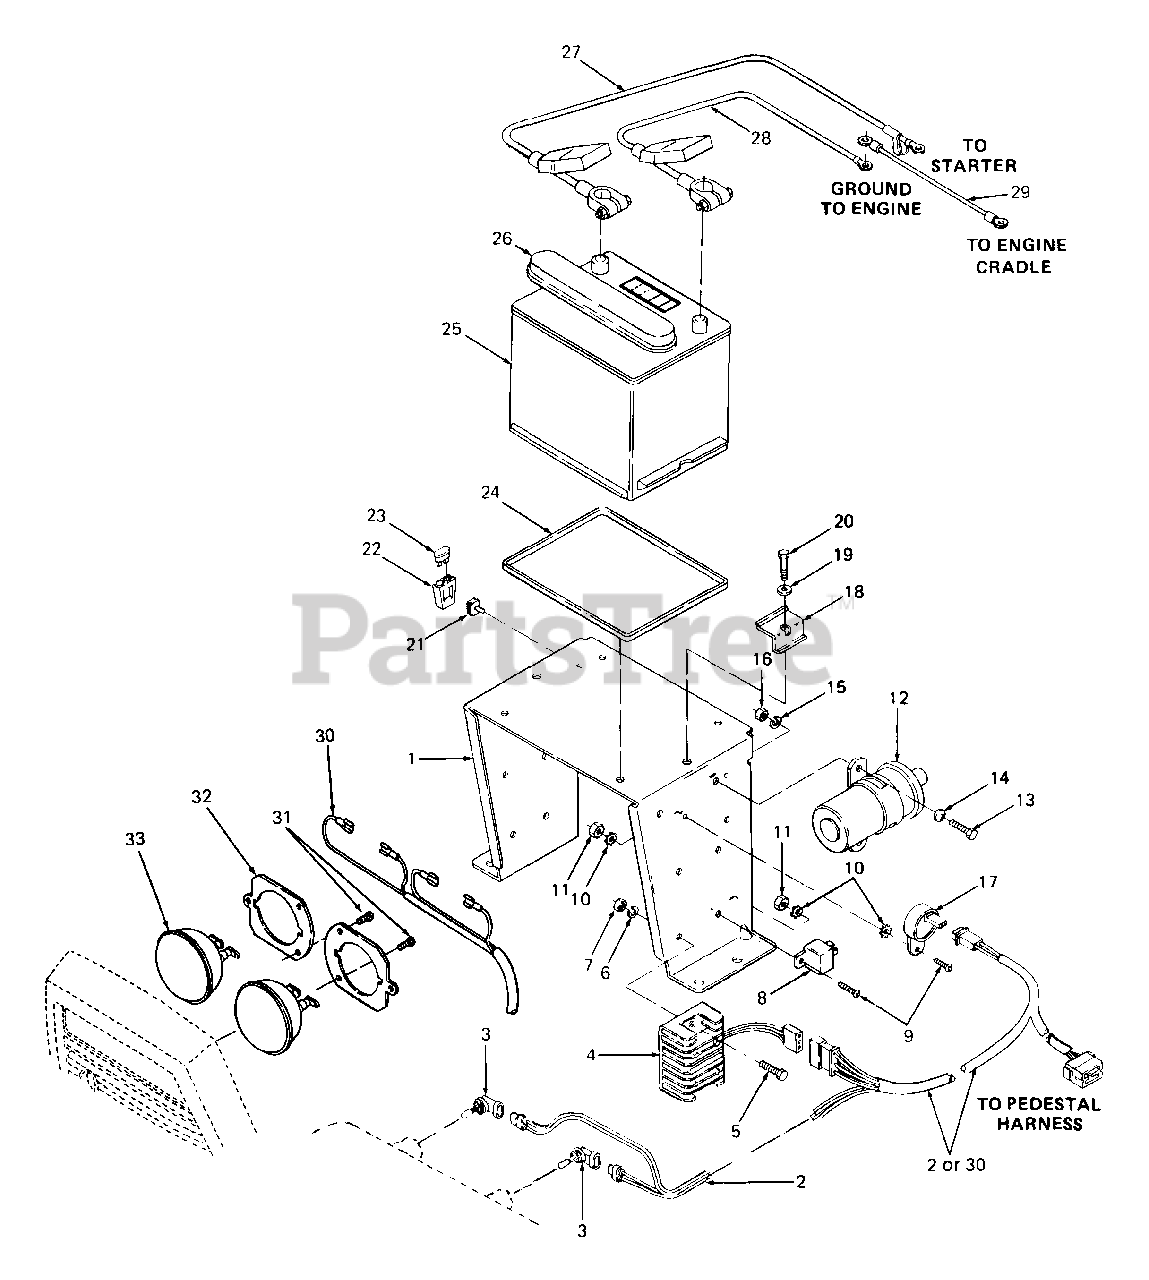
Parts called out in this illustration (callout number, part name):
1	Tray Assy, Battery
2	Harness, Main
3	Bulb, Head Lamp
4	Rectifier
5	Screw, Hex Cap, 1/4-20 x 1.25 Lg
6	Washer, Lock, 1/4
7	Nut, Hex, 1/4-20 GR5
8	Relay
9	Screw, Truss Mach, #10-24 x .50 Lg
10	Washer, External, #10
11	Nut, Hex, #10-24
12	Coil, Ignition
13	Screw, Hex Cap, 5/16-18 x .75 Lg GR5
14	Washer, Bell, .345 x .88 x .060 Thk
15	Washer, Lock, 5/16
16	Nut, Hex, 5/16-18 GR5
17	Indicator, Voltage
20	Screw, Hex Cap, 5/16-18 x 2.0 Lg
21	Clip, Fuse Holder Mtg
22	Holder, Fuse
23	Fuse, 20 Amp
24	Tray, Battery
25	Battery
26	Cap, Battery Vent
27	Cable, Positive Battery
28	Cable, Negative Battery
29	Cable, Ground
30	Harness, Main Wire
31	Screw, Pan Hd Tapp, #12 x .50 Lg
33	Headlamp, Sealed Beam
